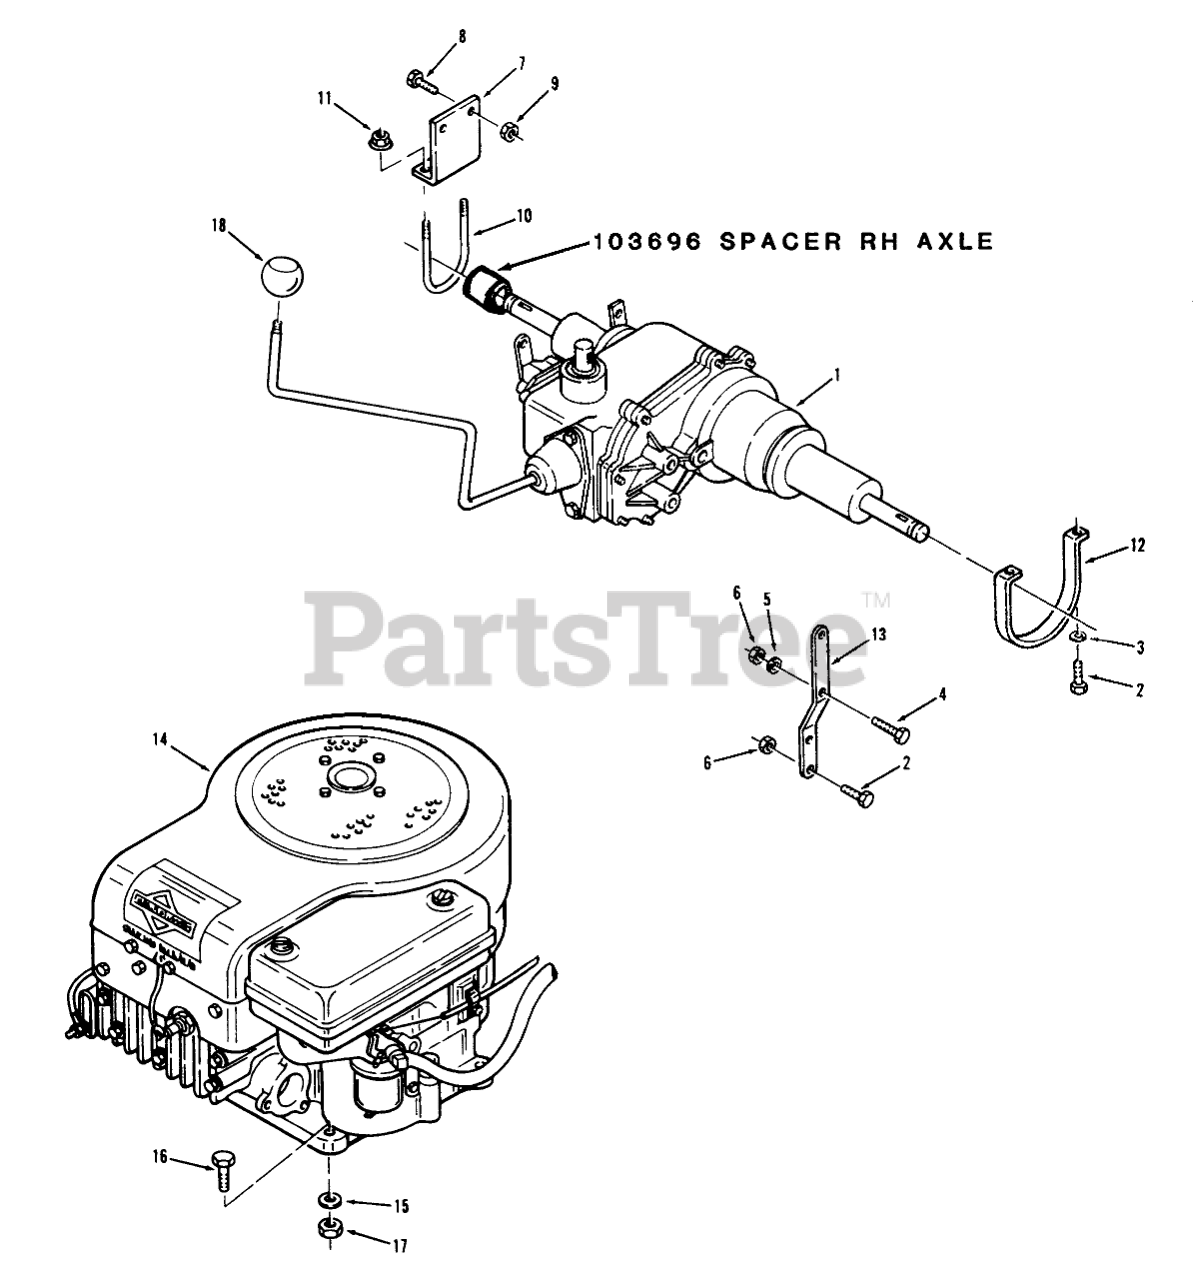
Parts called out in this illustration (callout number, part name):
1	Assy-Transmission
2	Bolt
3	Lockwasher
4	Bolt
5	WASHER 5/16 SAE
6	Nut
7	Bracket-Trans. Mtg.
8	Bolt
9	Nut
10	"U" Bolt Axle Mount
11	LOCKNUT-FLANGE
12	Girth-Transmission
13	Bar-Trans Support
14	Engine-10 HP Briggs
14	Engine-8 HP Briggs
15	WASHER 5/16 SAE
16	Bolt
17	Nut
18	SHIFT KNOB
